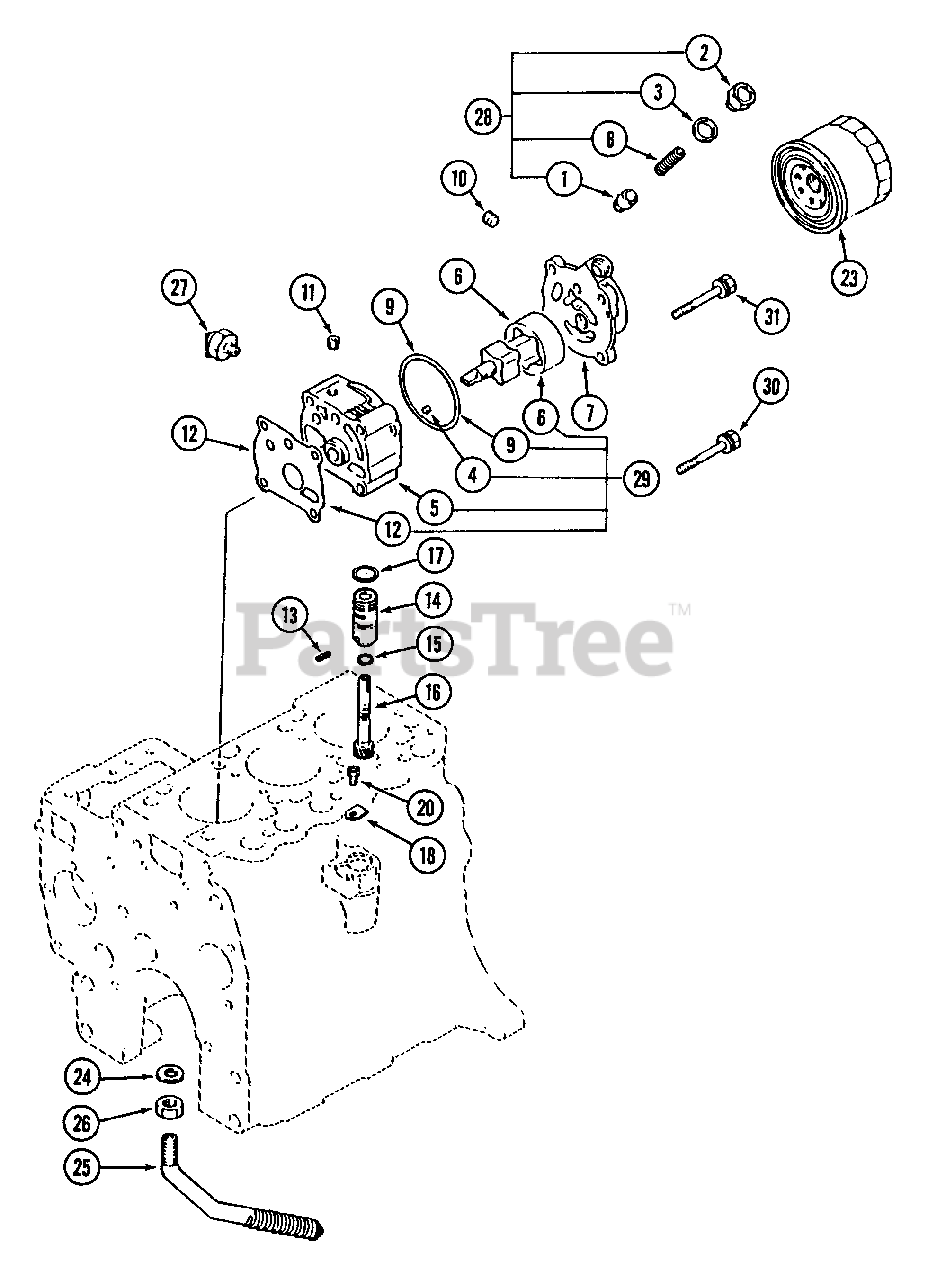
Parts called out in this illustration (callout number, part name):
1	Plunger, Relief
2	Plug, Relief
4	Pin, Dowel
5	Body, Oil Pump
6	Rotor Ass'y.
7	Cover, Oil Pump
8	Spring, Relief
12	Gasket, Oil Pump
13	Pin, Spring
14	Sleeve, Gear
16	Gear, Driven
17	O-Ring
18	Plate, Locking
20	Bolt, w/Washer
23	Oil Filter Ass'y.
24	Washer, Seal
25	Oil Screen Ass'y.
27	Oil Pressure Switch Ass'y.
28	Service Kit, Relief Valve
29	Service Kit, Rotor
30	Bolt, Washer Ass'y.
31	Bolt, Washer Ass'y.
